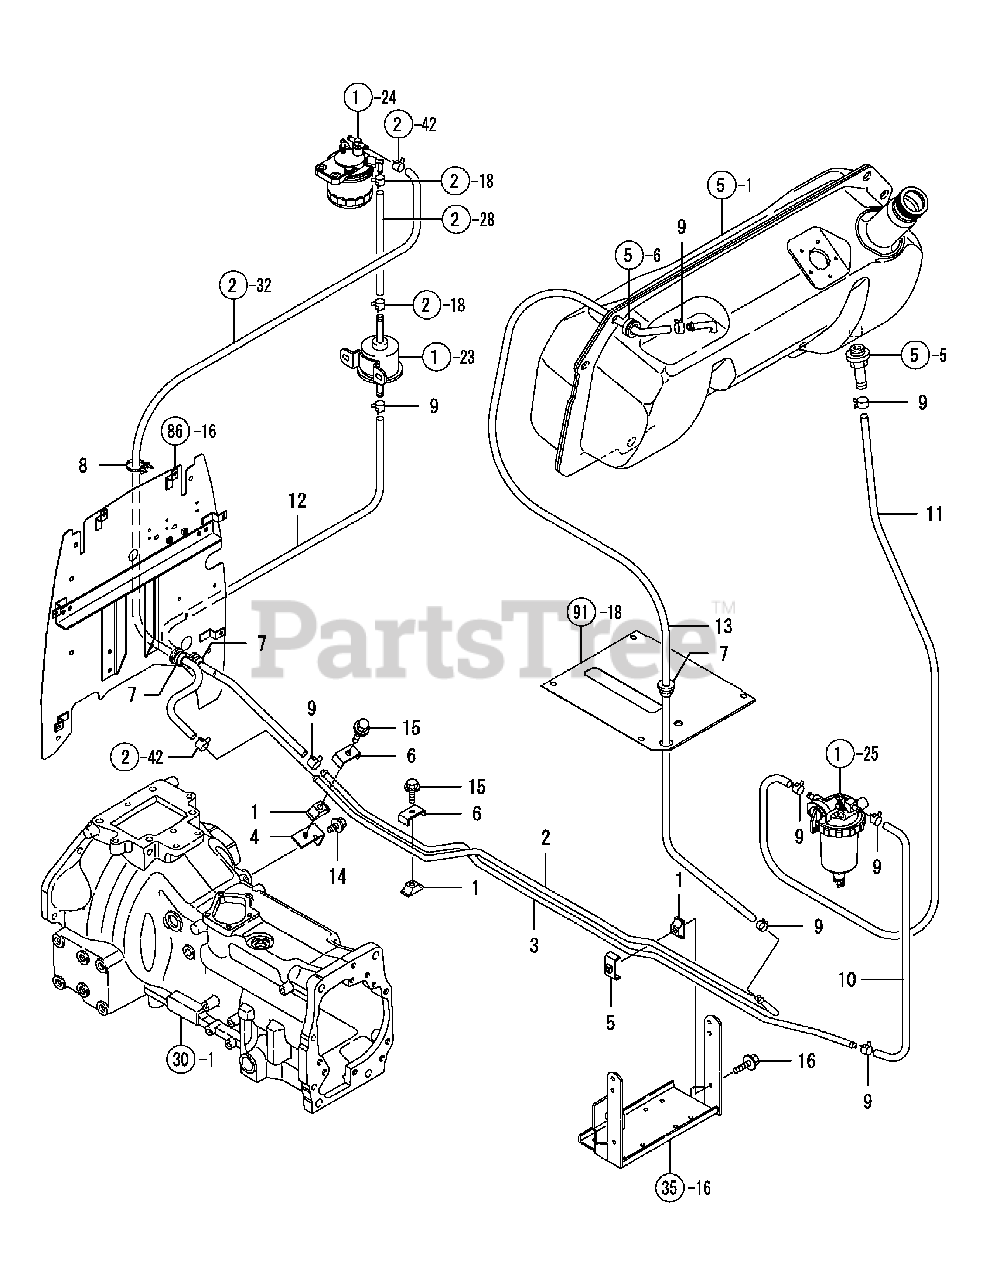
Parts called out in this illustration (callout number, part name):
1	BASE, PIPE CLAMP
2	PIPE, FUEL OIL
3	PIPE, FUEL OIL
4	BRACKET,FUEL PIPE
7	GROMMET 25
10	FUEL PIPE 7.3X300
11	FUEL PIPE 7.3X 420
12	FUEL PIPE 7.3X450
13	FUEL PIPE 7.3X1200
14	BOLT M 8X 16 PLATED
15	BOLT M 8X 25 PLATED
16	BOLT M 8X 30 PLATED
